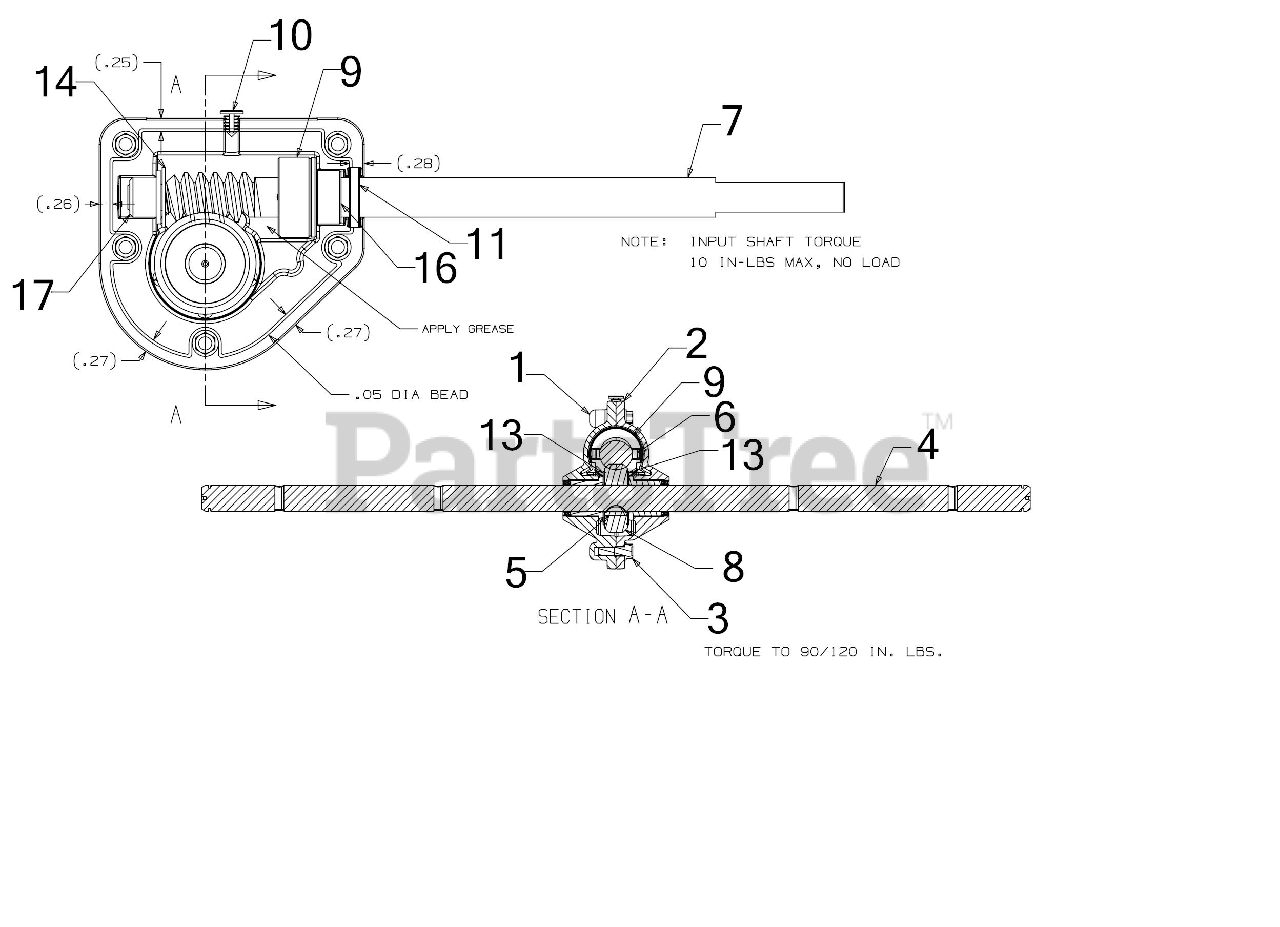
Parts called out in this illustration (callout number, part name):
1	REDUCER HOUSING ASSEMBLY (RH)
2	REDUCER HOUSING ASSEMBLY (LH)
3	SCREW 1/4-20 x .750
4	24" AUGER SHAFT
5	KEY 3/16 x 5/8 H
7	WORM SHAFT
8	WORM GEAR 20T
9	COLLAR-THRUST .756ID x .600
11	OIL SEAL .75 x 1.131 x .188
13	THRUST WASHER
14	FLAT WASHER
16	FLANGE BEARING
17	FLANGE BEARING
